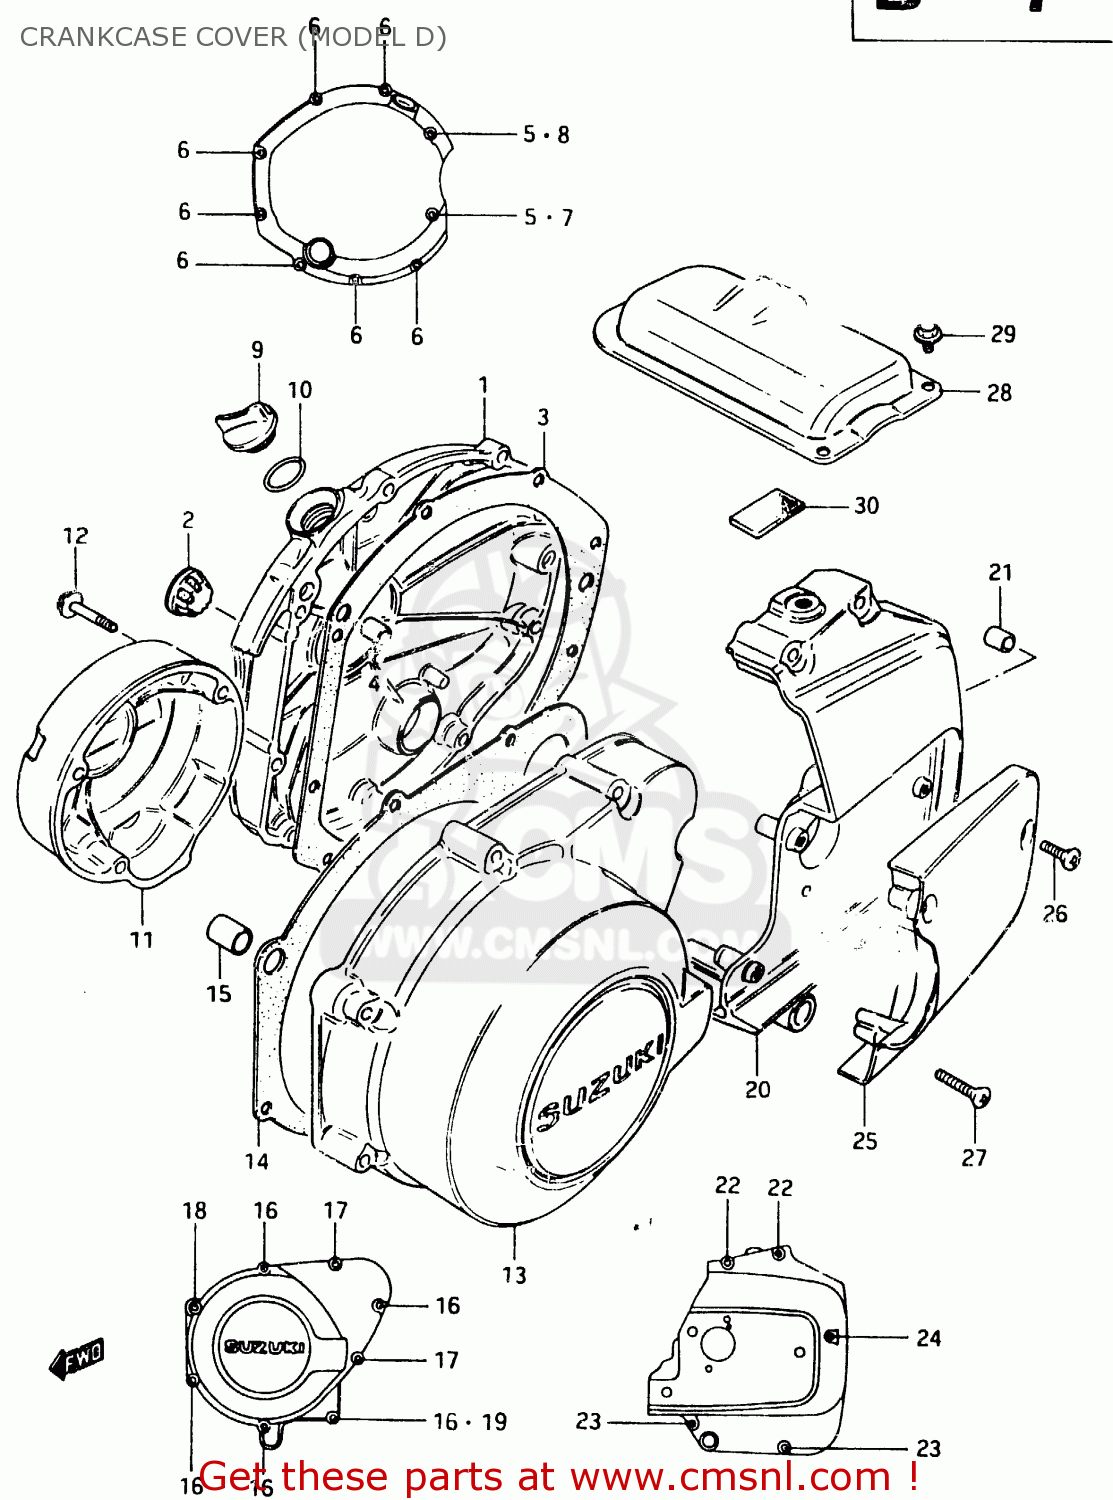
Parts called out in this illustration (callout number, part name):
1	COVER,CLUTCH
2	LENS,OIL LEVEL CHECK
3	GASKET,CLUTCH COVER (MCA)
4	PIN
5	WASHER
6	BOLT
7	BOLT (6X30)
8	BOLT (6X35)
9	PLUG(20X10)
10	O RING(D:3.1,ID:16.8)
11	COVER,CONTACT BRAKER
12	BOLT (5X30)
13	COVER,MAGNETO
14	GASKET,MAGNETO COVER (MCA)
15	PIN (11X20)(SUS)
16	BOLT (6X35)
17	BOLT (6X40)
18	BOLT
19	WASHER
20	COVER,ENGINE SPROCKET
21	PIN
22	BOLT (6X40)
23	BOLT (6X50)
24	BOLT (6X70)
25	CAP,CLUTCH RELEASE ADJUST
26	SCREW
27	SCREW
28	COVER,STARTER MOTOR
29	BOLT
30	DAMPER,STARTER MOTOR CLUTCH
